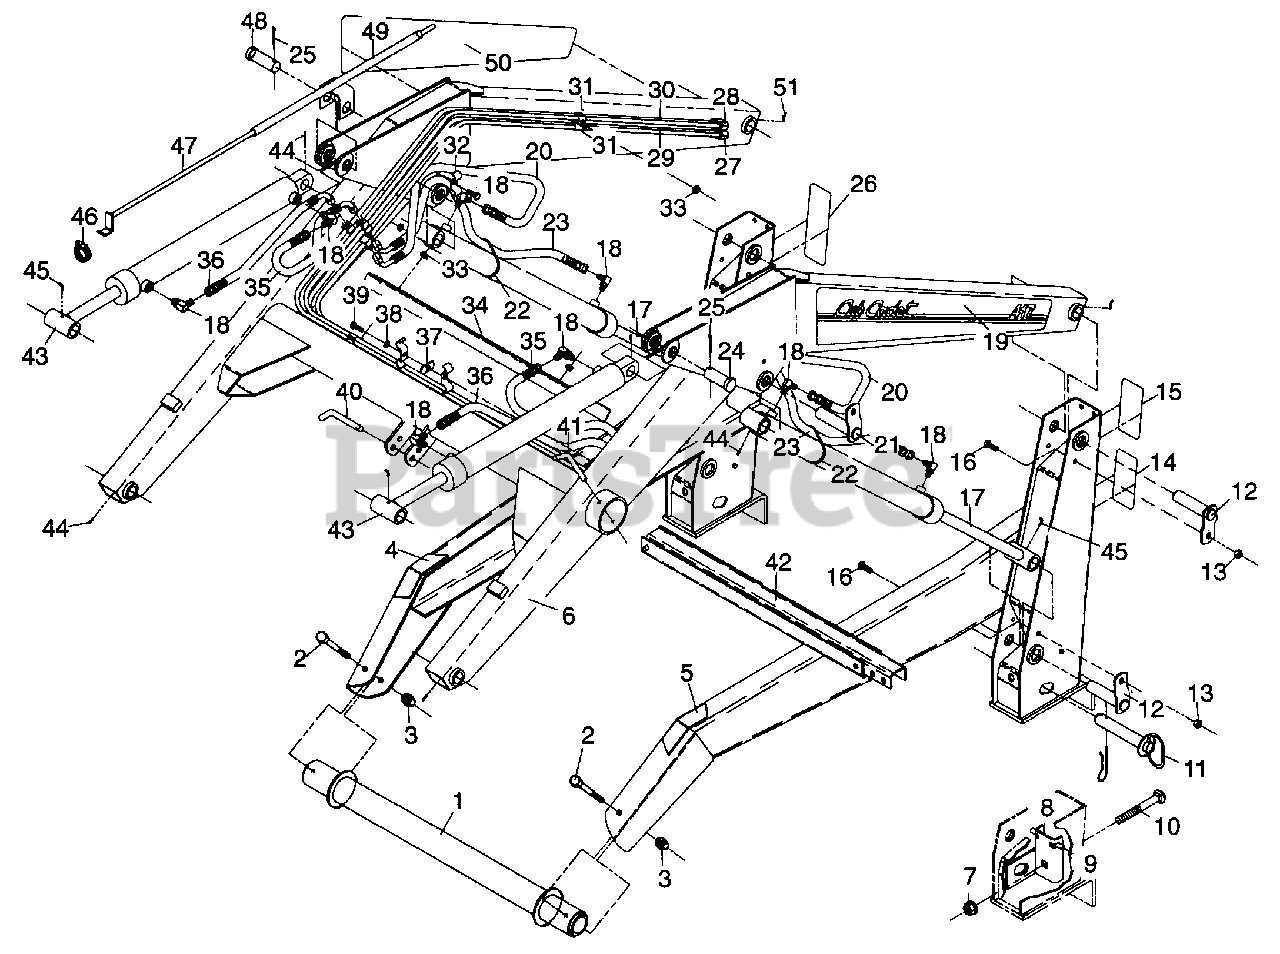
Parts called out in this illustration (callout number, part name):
1	Crossbar Weldment
2	5/8 NC x 3-3/4 Capscrew
3	5/8 NC Locknut
4	Main frame assembly - RH
5	Main frame assembly - LH
6	Boom frame assembly
7	5/8 NC Locknut - Flange Head
8	Retainer Channel
9	Pin (Must be Welded)
10	5/8 NC x 5 Carriage bolt, plated
11	Handle Hitch Pin
12	Pin weldment
13	3/8 NC Lockpin
14	Danger decal
15	Decal - Caution
16	3/8 NC x 1 Capscrew
17	Cylinder Assembly Lift
18	90° Adjustable elbow
19	Decal - 417
20	Pressure Hose - L-28
21	Pin weldment
22	Plastic Tie
23	Pressure Hose - L-40
24	Clevis Pin - 1 x 2-19/64
25	3/16 x 1-1/2 Cotter pin
26	Instruction Decal
27	Feedline #3
28	Feedline #1
29	Feedline #4
30	Feedline #2
31	Feedline Clamp
32	Feedline Clamp
33	5/16 NC Locknut, flange head
34	Feedline Cover
35	Pressure Hose L-15
36	Pressure Hose L-20
37	Tab Weld Nut
38	5/16 Lockwasher
39	5/16 NC x 3/4 Capscrew
40	Bent Pull Pin w/Hair Pin Cotter
41	Bent Pull Pin w/Hair Pin Cotter
42	Stand Weldment
43	Cylinder Assembly - Tilt
44	1/4-28 Lube fitting
45	1/4-28 x 90° Lube fitting
46	Hose Clamp - 5/8 - 1-1/2
47	Rod weldment
48	Clevis Pin - 1 x 2-35/64
49	Tube Weldment
51	1/4-28 x 45 Lube fitting
